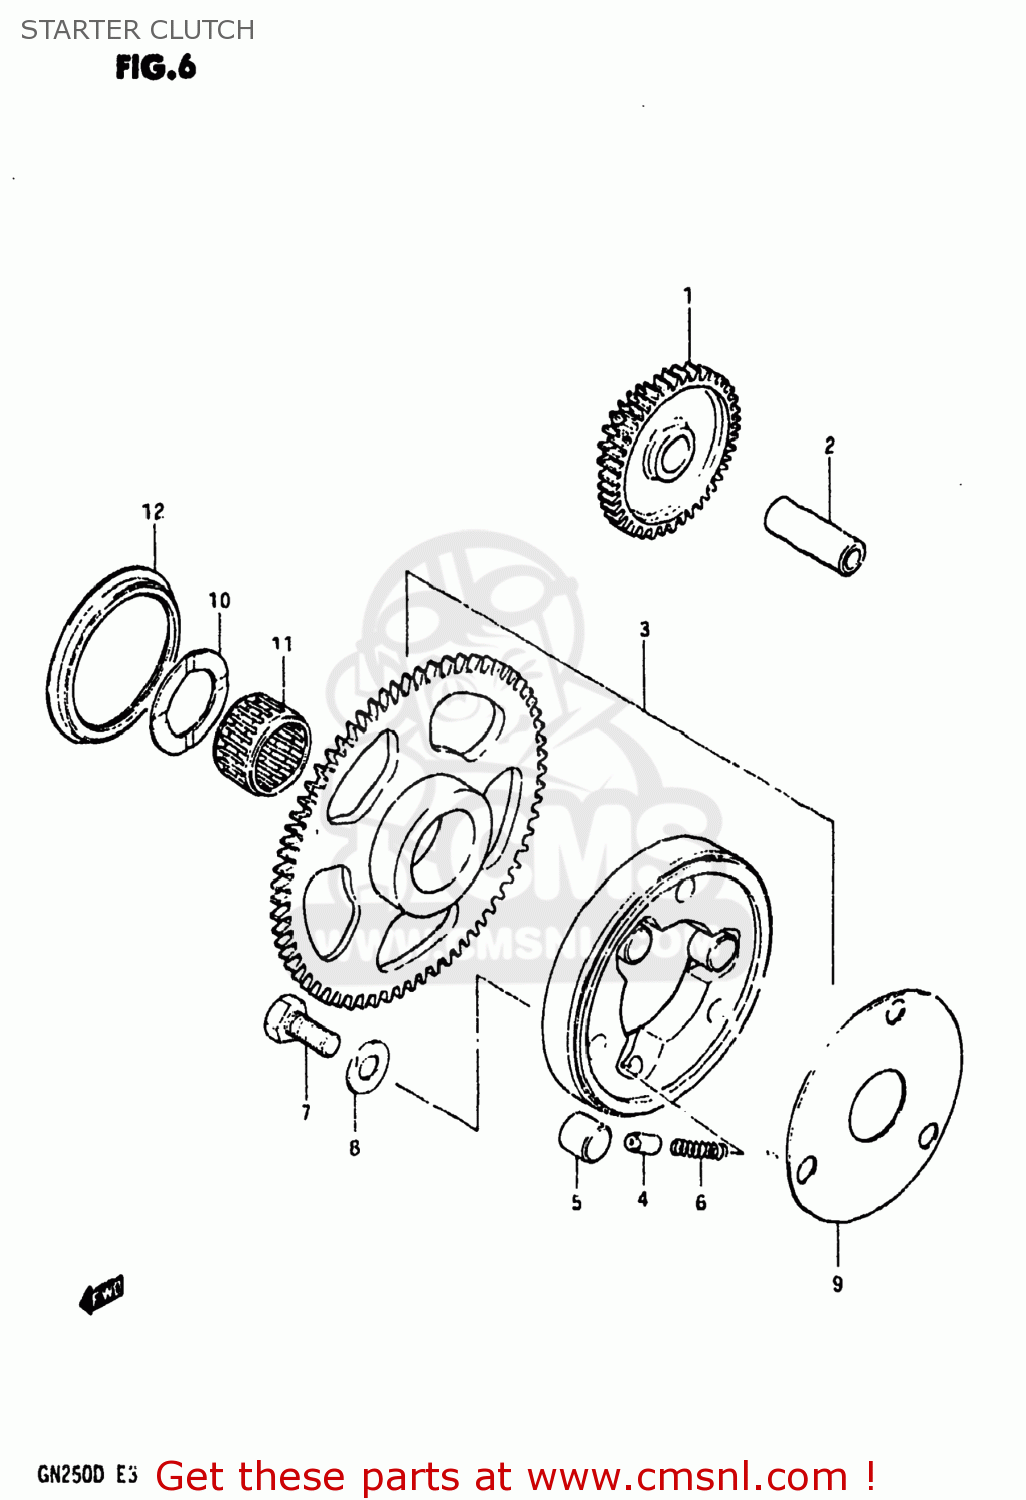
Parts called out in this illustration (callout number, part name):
1	GEAR,STARTER IDLE
2	PIN(7.4X13X40)
3	CLUTCH SET,STARTER
4	PIECE,PUSH
5	PIN(14X13)
6	SPRING
7	BOLT
8	WASHER
9	SHIM,STARTER CLUTCH HUB
10	WASHER(27X40X2.5)
11	BEARING(27X32X21.8)
12	OIL SEAL
